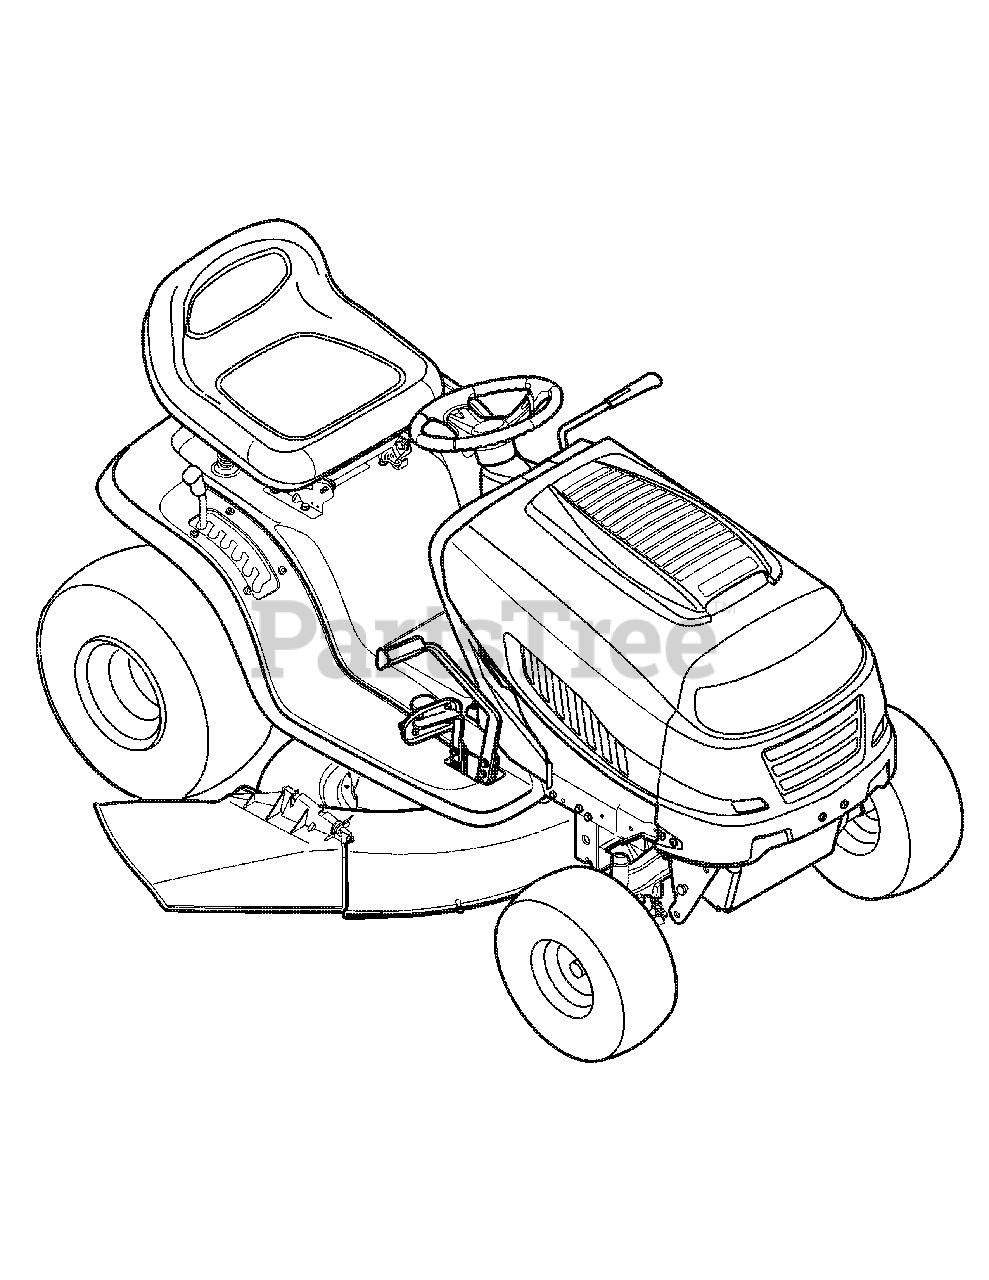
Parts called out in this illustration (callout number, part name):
NA	OIL FILTER
NA	PRE-CLEANER ELEMENT
NA	UPPER DRIVE BELT
NA	ENGINE TO DECK BELT
NA	WATER NOZZLE ADAPTER
